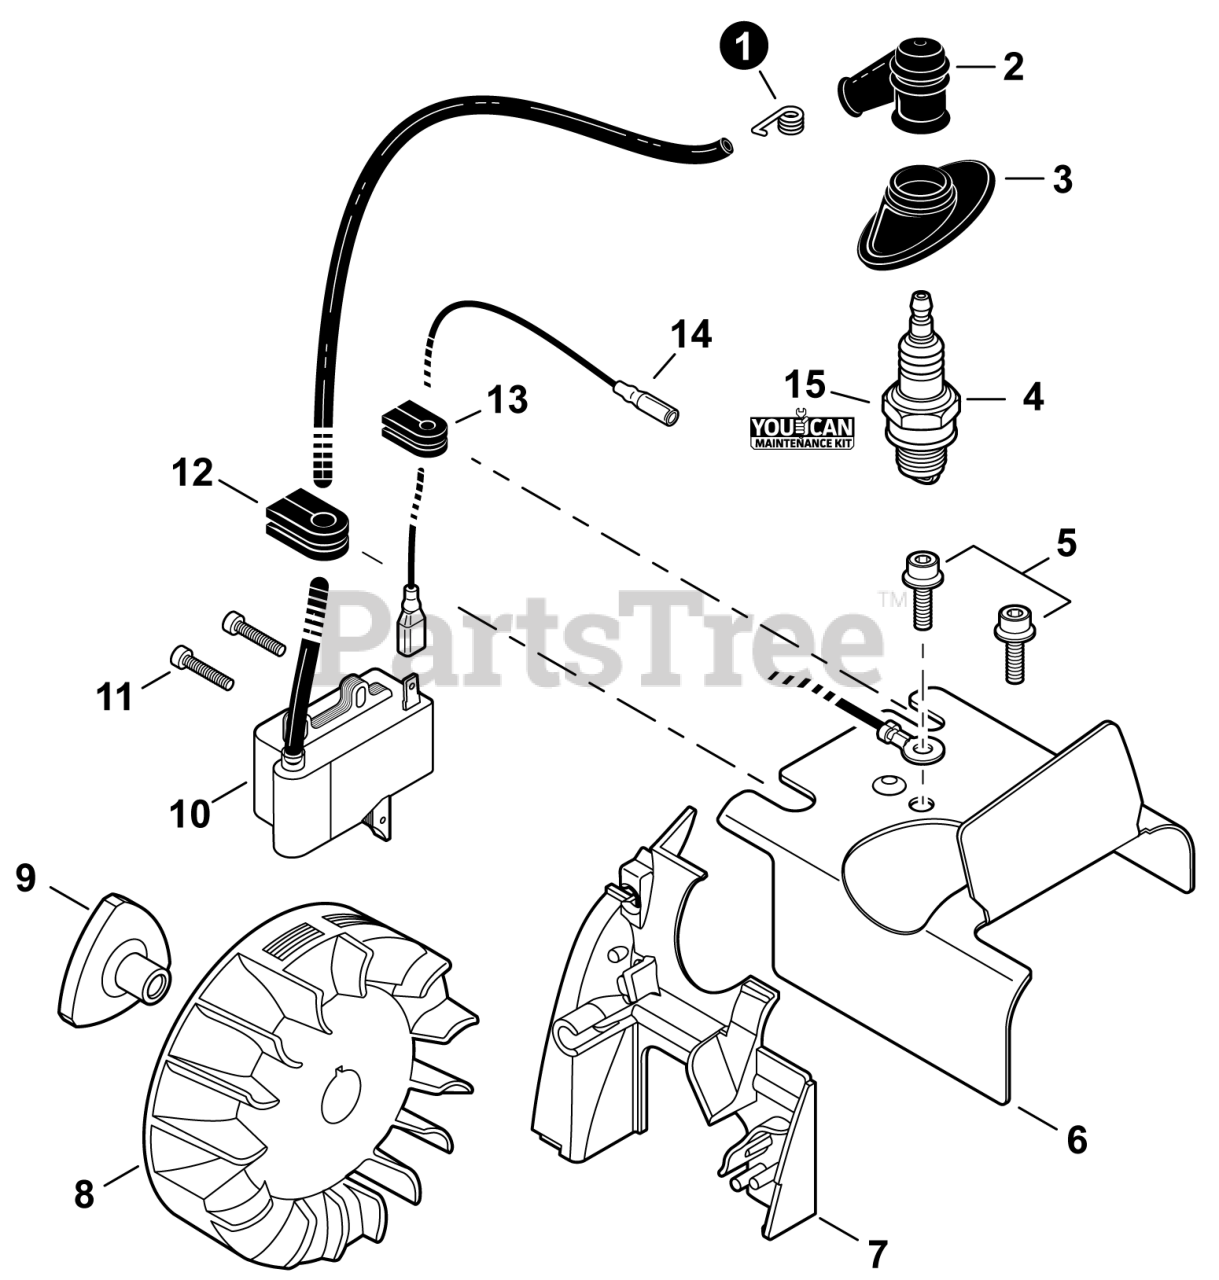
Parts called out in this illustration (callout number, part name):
1	TERMINAL, SPARK PLUG
2	CAP, SPARK PLUG
3	COVER, DUST
4	SPARK PLUG - BPM8Y
5	BOLT 5x8
6	COVER, CYLINDER
7	COVER, CYLINDER - NYLON
8	FLYWHEEL
9	HUB, FAN
10	COIL, IGNITION
11	BOLT 4x20
14	LEAD - IGNITION
15	TUNE-UP KIT - YOUCAN™
